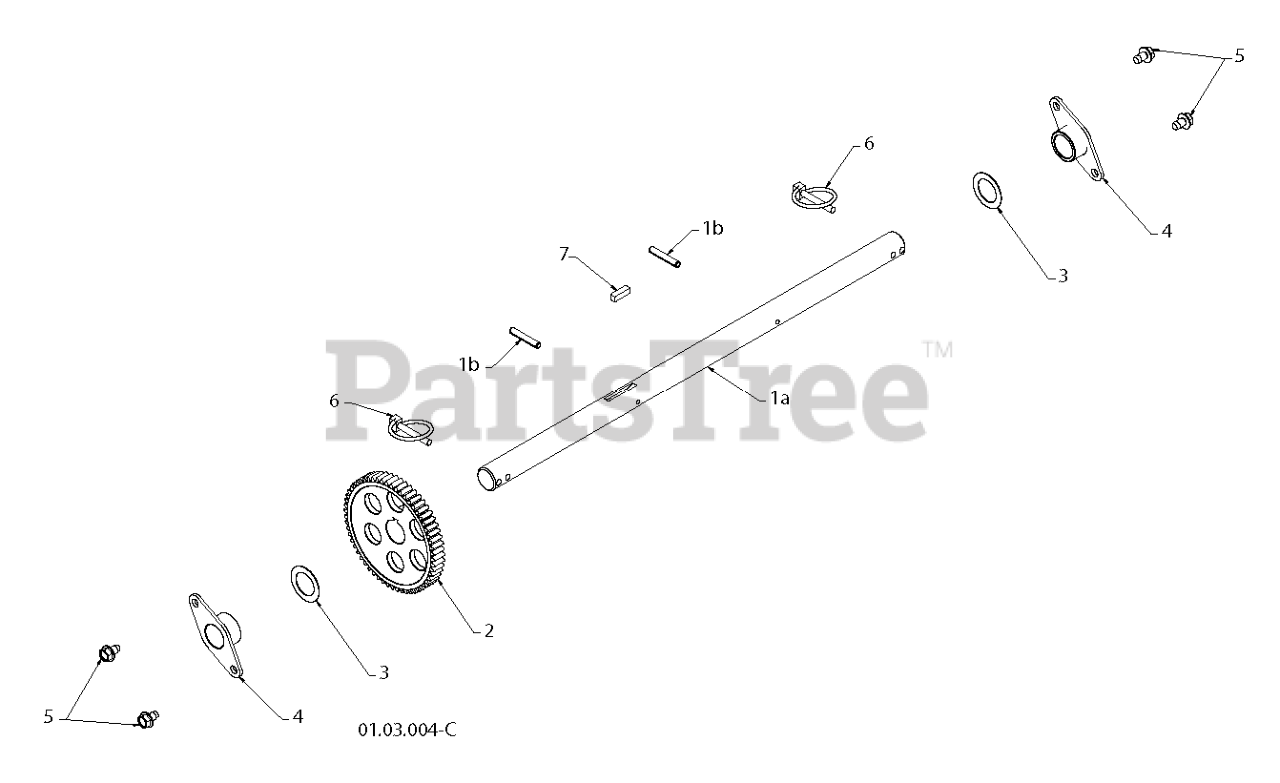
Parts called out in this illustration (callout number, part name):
1	AXLE.SHAFT.ASM.W/ROLPIN.NON-PS
1A	SHAFT.AXLE.16".SNOW
1B	PIN.ROLL.3/16
2	GEAR, AXLE (58T)
3	WASHER TRUST 1"
4	BEARING, AXLE
5	Screw 5/16-18 x 1/2 Hex, Self Tapping 5/16-18 x 1/2
6	PIN KLIK, 1/4
7	KEY, SQUARE 1/4 X .875
